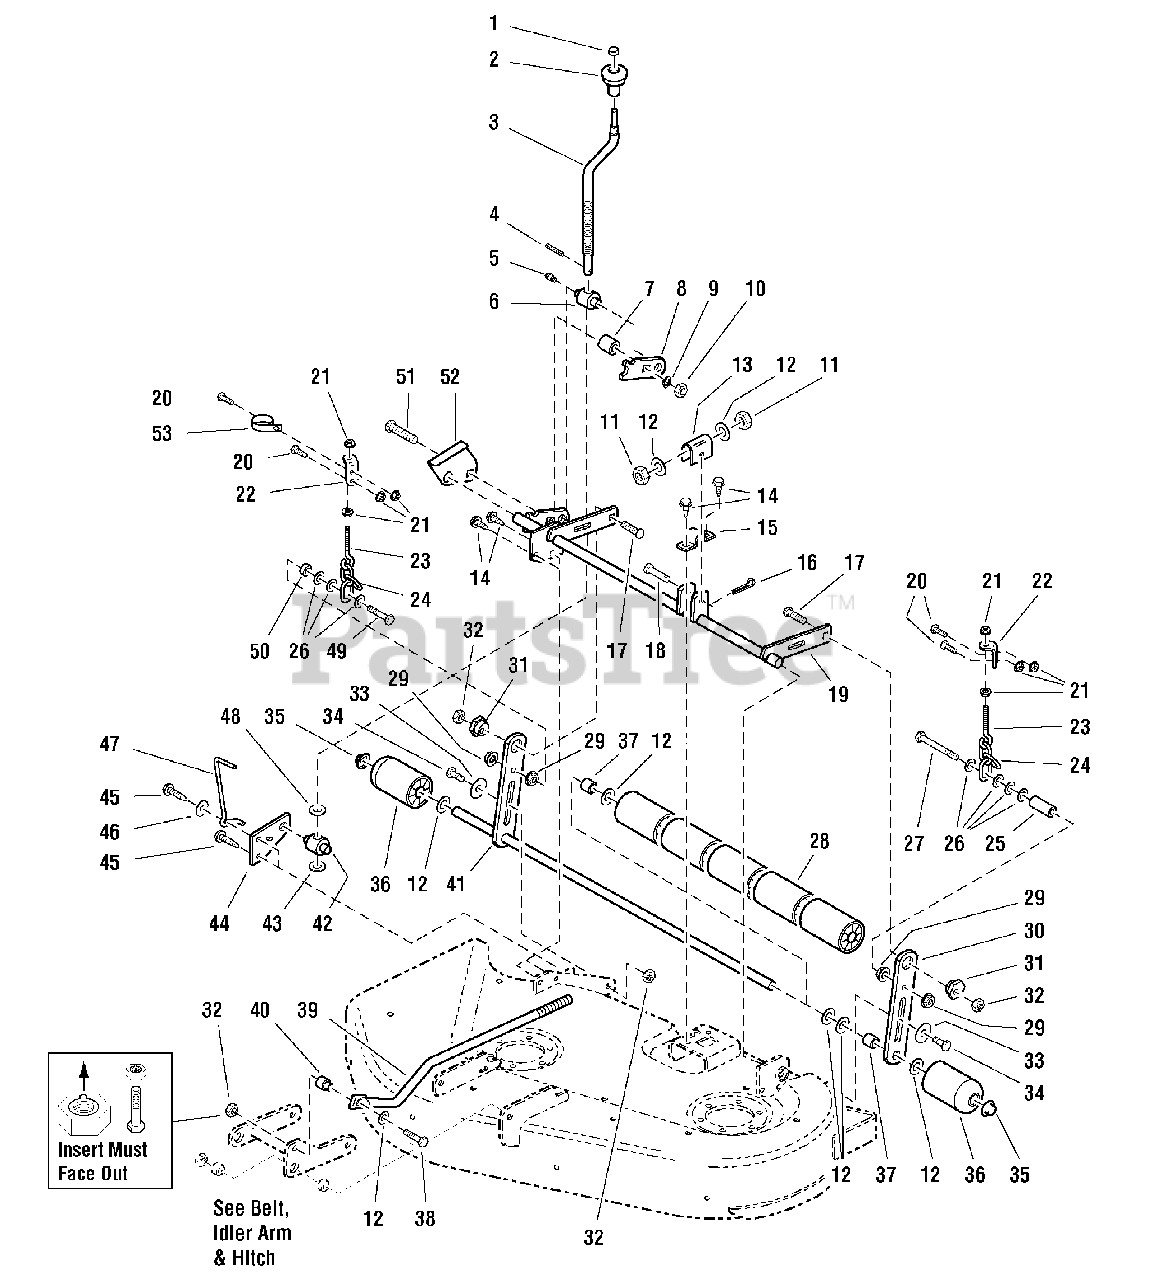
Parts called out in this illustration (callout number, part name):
1	NUT, Push, 3/8, Black
2	KNOB, Spinner
3	CRANK, Height Adjustment, Black
4	PIN, Spring
5	FITTING, Lube
8	ARM, Height Adjust
9	LOCKWASHER, 1/2
10	NUT, Hex, 1/2-13
11	NUT, Hex, 5/8-18
12	WASHER, 5/8
13	TRUNNION
14	CAPSCREW, Hex Washer Head, Taptite, 5/16-18 x 3/4, Black
15	STRAP
16	PIN, Cotter
17	CARRIAGE BOLT, 3/8-16 x 1-1/2
18	PIN, Clevis
19	SHAFT ASSEMBLY
20	CAPSCREW, Hex Head, 5/16-18 x 1
21	NUT, Hex Serrated Flange, 5/16-18
22	BRACKET, Rear Roller
24	CHAIN, 3 Links
26	WASHER, 3/8
27	CAPSCREW, Hex Head, 3/8-16 x 3-3/4, Black
29	NUT, Hex Serrated Flange, 3/8-16
30	BAR, Roller
31	NUT, Hex Adjusting, .99 DIA .687
32	NUT, Hex Lock, Aluminum Insert, 3/8-16
33	WASHER, 1/2
34	BOLT, Shoulder, 3/8-16 X 1.34
35	NUT, Push, 5/8, Black
36	ROLLER, End
37	SPACER, .66 ID
38	CAPSCREW, Hex Head, 3/8-16 x 1-3/4
41	SHAFT & BAR ASSEMBLY
43	WASHER, Detent, Black
45	CAPSCREW, Hex Washer Head, Taptite, 5/16-18 x 1-1/4, Black
46	WASHER, 5/16, Black
47	ROD, Height of Cut
48	WASHER, 1/2, Black
49	CAPSCREW, Hex Head, 3/8-16 x 2
51	CARRIAGE BOLT, 1/2-13 x 2-1/2, Black
52	BRACKET, Height of Cut
